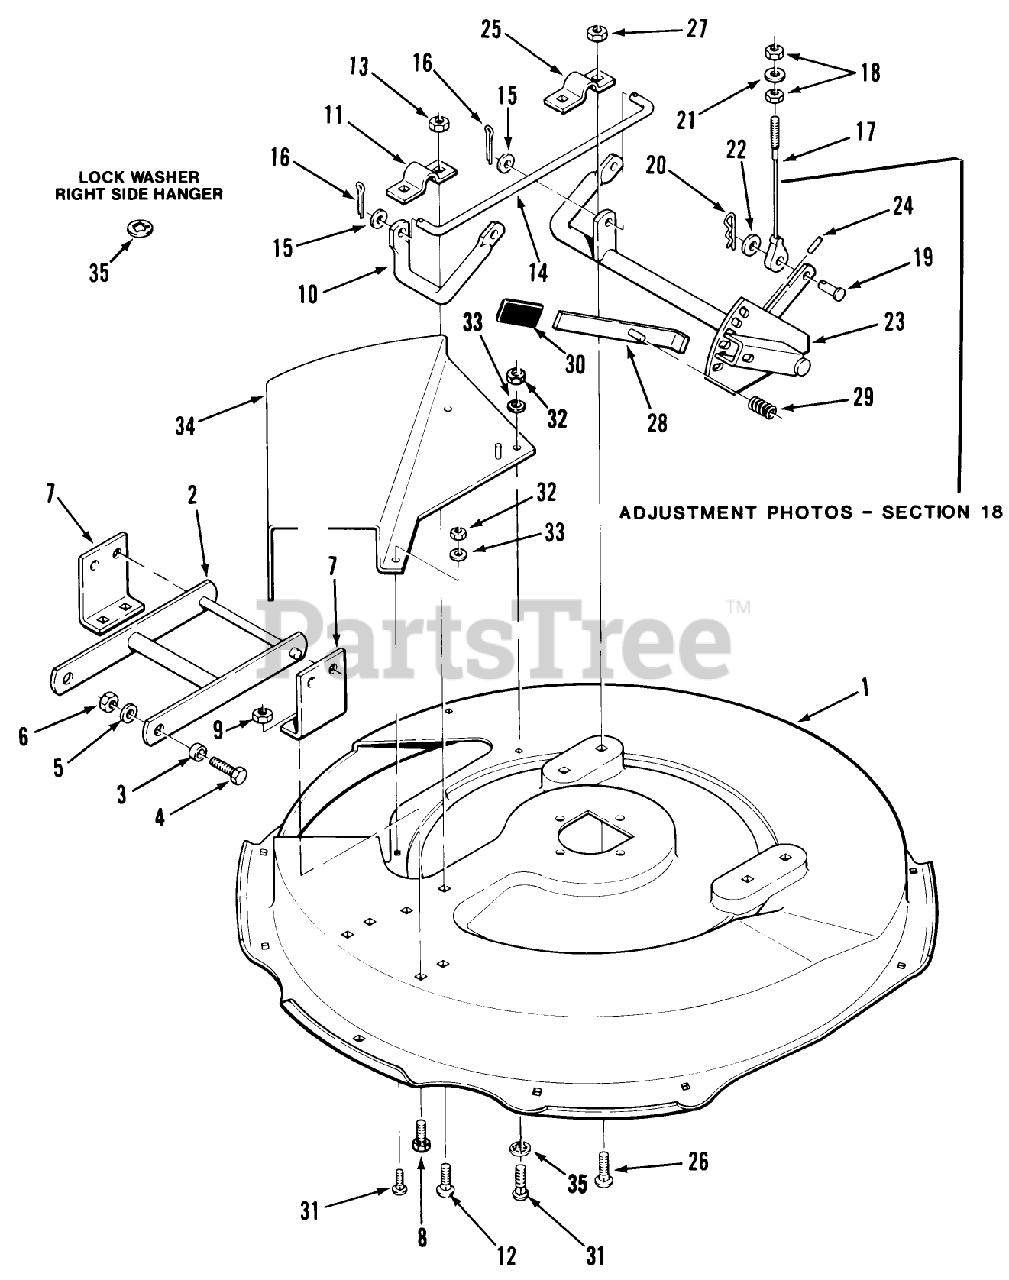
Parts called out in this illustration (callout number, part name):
3	SPACER
7	BRKT FRONT MOWER *R
11	CLAMP
17	CABLE MOWER SUPPORT
20	Hairpin
21	WASHER 5/16 SAE
24	SPIROL PIN
25	CLAMP
28	LEVER ASSY
29	SPRING-COMPRESSION
